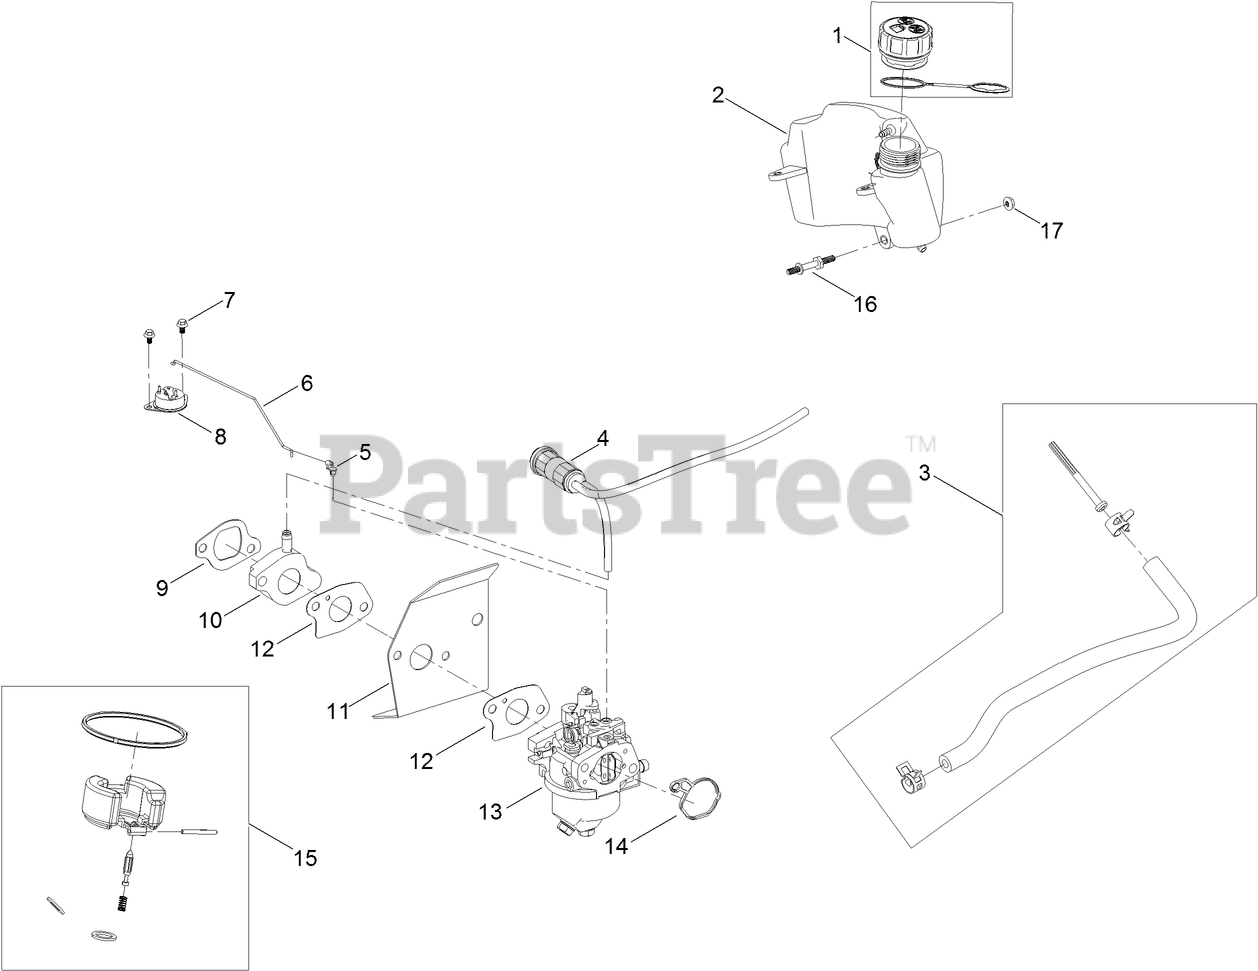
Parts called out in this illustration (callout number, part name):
1	CAP-FUEL, SEALED
2	TANK-FUEL
3	FUEL LINE KIT
4	CANISTER-CARBON, 19 CC
5	LOCK-THROTTLE
6	LINKAGE-CHOKE, THERMAL
7	SCREW-HWHTF
8	CONTROL-THERMAL
9	GASKET-INTAKE
10	SPACER-CARBURETOR
11	INSULATOR-CARBURETOR
12	GASKET-CARBURETOR
13	CARBURETOR
14	GASKET-CARBURETOR
15	INTERNAL CARB SERVICE KIT
16	BOLT-STUD
17	NUT-FLANGE
